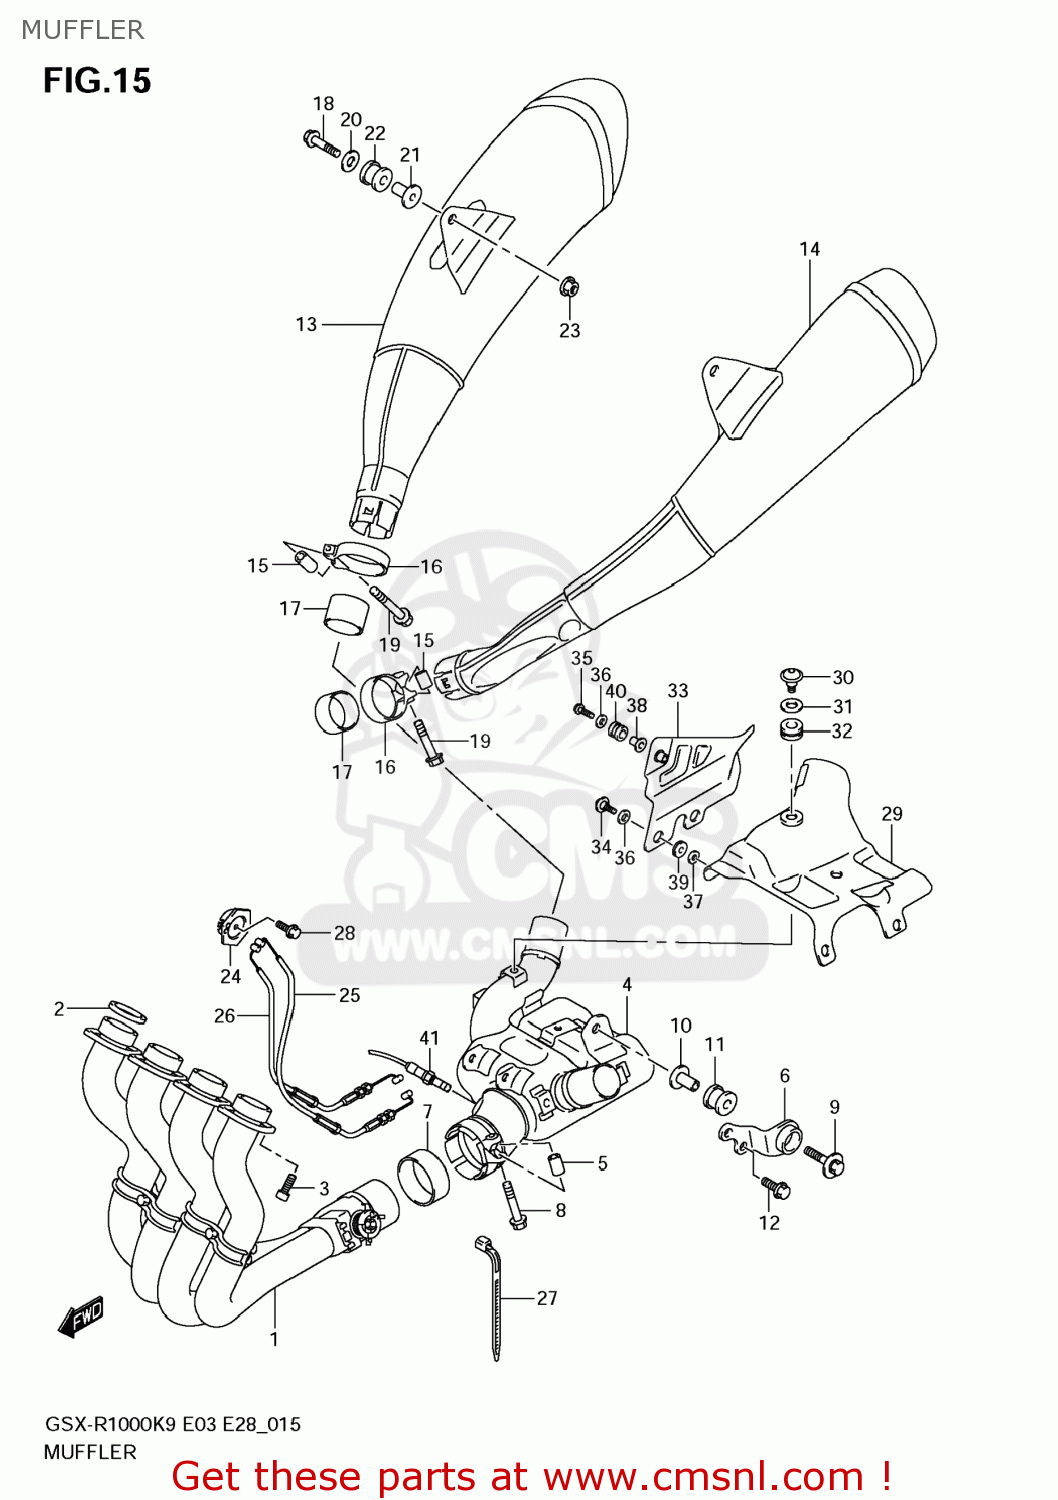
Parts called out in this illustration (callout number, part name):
1	PIPE,EXHAUST
2	GASKET,EXHAUST PIPE (NAS)
3	BOLT(8X25)
4	CHAMBER
5	SPACER,MUFFLER
6	BRACKET,CHAMBER SPRT
7	CONNECTOR,CHAMBER
8	BOLT(8X40)
9	BOLT 8X45
10	SPACER(8.6X12X24.2)
11	CUSHION
12	BOLT
13	BODY,MUFFLER,R
14	BODY,MUFFLER,L
15	SPACER,MUFFLER
16	CLAMP,MUFFLER CONNECTOR
17	CONNECTOR,MUFFLER
18	BOLT(8X45)
19	BOLT(8X40)
20	WASHER(8.5X28X1.5)
21	SPACER(8.6X12X24.2)
22	CUSHION
23	NUT
24	PULLEY CONTROL
25	CABLE,EXHAUST VALVE NO.1
26	CABLE,EXHAUST VALVE NO.2
27	CLAMP(L:125)
28	BOLT
29	GUARD,CHAMBER HEAT NO.1
30	SCREW(6X12)
31	WASHER(8.5X18X1)
32	CUSHION
33	GUARD,CHAMBER HEAT NO.2
34	SCREW(6X20)
35	SCREW(6X25)
36	WASHER(6.5X15X1.0)
37	WASHER
38	SPACER(6.2X8.4X10.9)
39	CUSHION
40	CUSHION
41	SENSOR,OXYGEN
